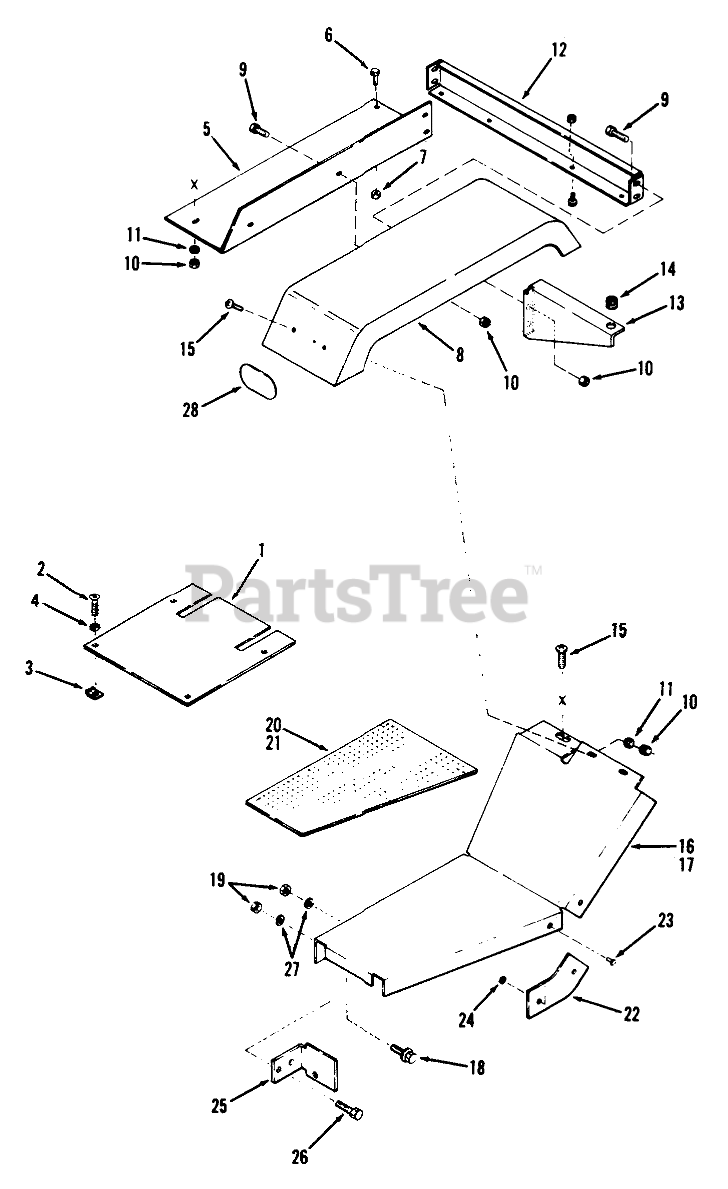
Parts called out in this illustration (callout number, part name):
1	Access Cover Plate
2	Screw-Hex HD Slotted
3	Speed Nut
4	LOCKWASHER
5	Plate-Fender RH
5	Plate-Fender LH
6	Bolt
7	Nut
8	Fender
9	Bolt
10	Nut
11	WASHER 5/16 SAE
12	Channel
13	Wear Plate
14	Bumper
15	Screw
16	Footrest RH
17	Footrest LH
18	BOLT
19	Nut
20	Footrest Mat RH
21	Footrest Mat LH
22	Filler Plate
23	RIVET
24	WASHER
25	Bracket
27	Washer
28	Reflector
